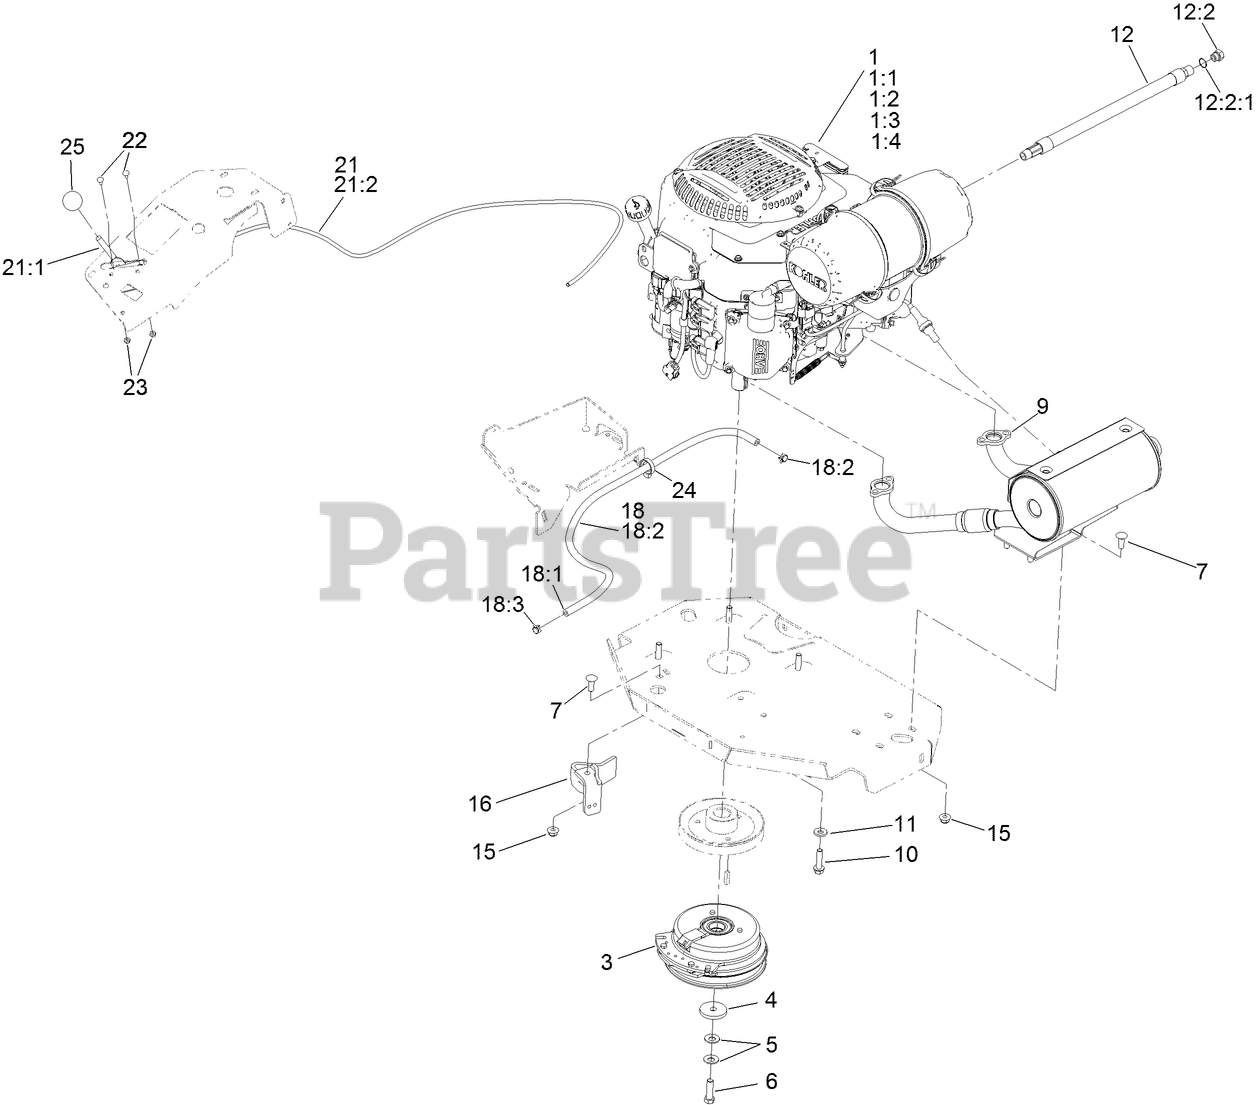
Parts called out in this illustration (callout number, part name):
1:1	KOHLER 52 050 02-S ENGINE OIL FILTER
1:2	KOHLER 25 083 01-S ENGINE AIR FILTER
1:3	KOHLER 25 083 04-S SAFETY FILTER
1:4	KOHLER 25 050 42-S FUEL FILTER
3	CLUTCH KIT
4	WASHER-CLUTCH
5	WASHER-SPRING
6	SCREW-HH, W/LOCTITE
7	SCREW-CARR
9	KIT,MUFFLER
10	SCREW-HWH
11	WASHER-BELLEVILLE
12	OIL DRAIN HOSE ASM
12:2	PLUG-HH
12:2:1	O-RING
15	NUT-HF, NI
16	CLUTCH-ANCHOR
18	FUEL LINE ASM
18:1	HOSE-FUEL
18:2	SLEEVE-THERMAL
18:3	CLAMP-HOSE
21	THROTTLE CONTROL ASM
21:1	LEVER-THROTTLE
22	BOLT-CARR
23	NUT-LOCK, NI
24	CLAMP-HOSE
25	KNOB-BALL
